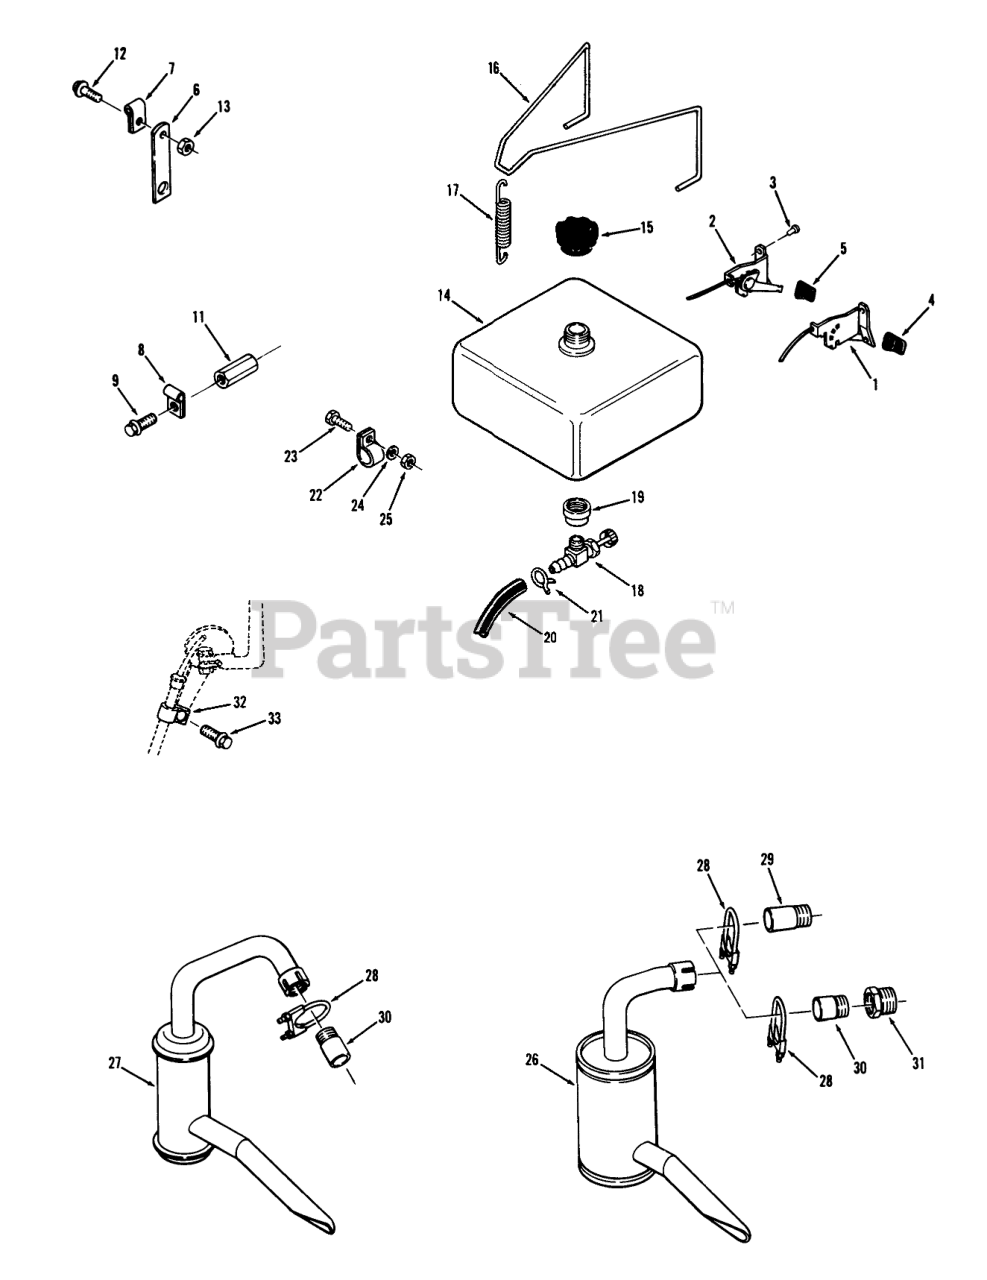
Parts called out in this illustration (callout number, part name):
1	Choke Control
2	THROTTLE CONTROL
3	RIVET-4
4	KNOB-CHOKE
5	KNOB-THROTTLE
6	Strap
7	THROTTLE CONTROL CLP
8	Clip
9	Screw
11	Special Nut
12	Screw
12	Bolt
13	Nut
14	ASSY-FUEL TANK
15	Cap
16	HOLD DOWN WIRE
17	CLUTCH SPRING
18	VALVE-FUEL
19	BUSHING
20	Fuel Line
21	Clamp
22	CLAMP-HOSE
23	Bolt
24	WASHER 5/16 SAE
25	Nut
26	Muffler
27	Muffler Assy
28	ASSY-MUFFLER CLAMP
29	NIPPLE
30	NIPPLE- 1X2 SPECIAL
31	REDUCER 1 1/4-1
32	CLIP-CABLE
33	Screw
